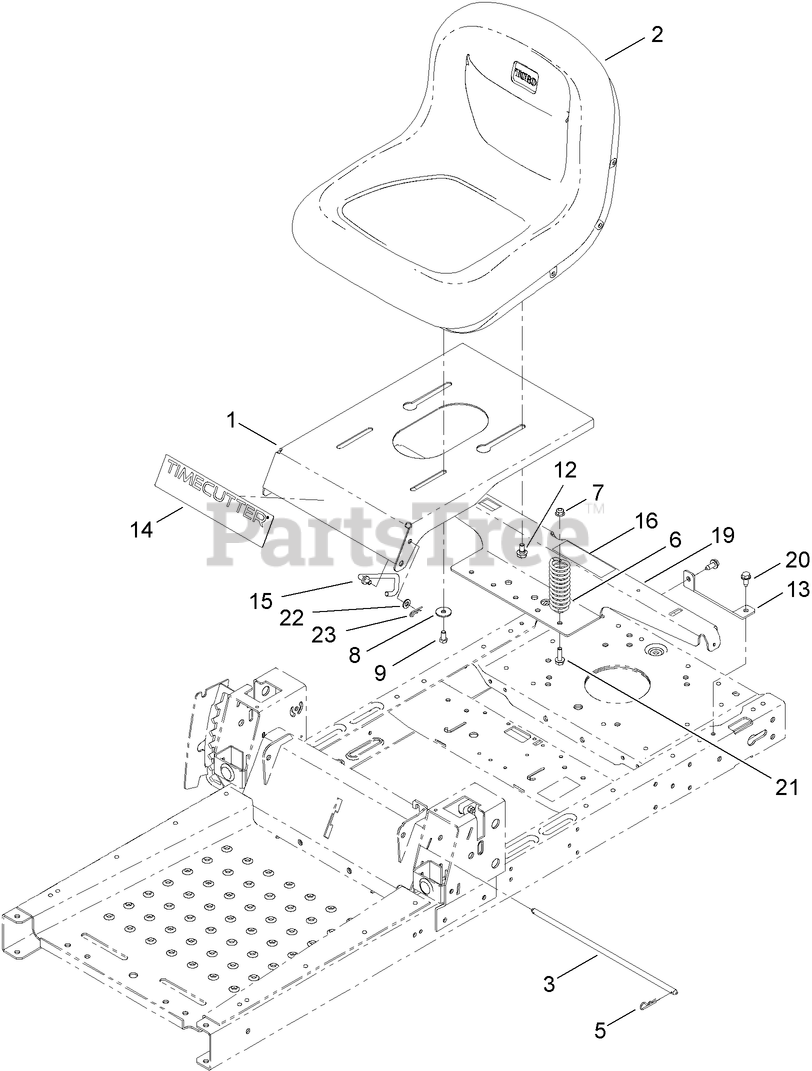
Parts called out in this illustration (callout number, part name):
2	SEAT-15 INCH
3	ROD-PIVOT, NARROW
5	PIN-COTTER
6	SPRING-COMPRESSION
7	NUT-HF, NI
8	WASHER-PIVOT
9	SCREW-HH
12	BOLT-SHOULDER,HFH
13	SUPPORT-TANK, REAR
14	DECAL-TIMECUTTER
15	STOP-SEAT
16	DECAL-SERVICE, CE
19	SUPPORT-POD
20	SCREW-HWHTF
21	SCREW-HHF
22	WASHER-PLAIN
